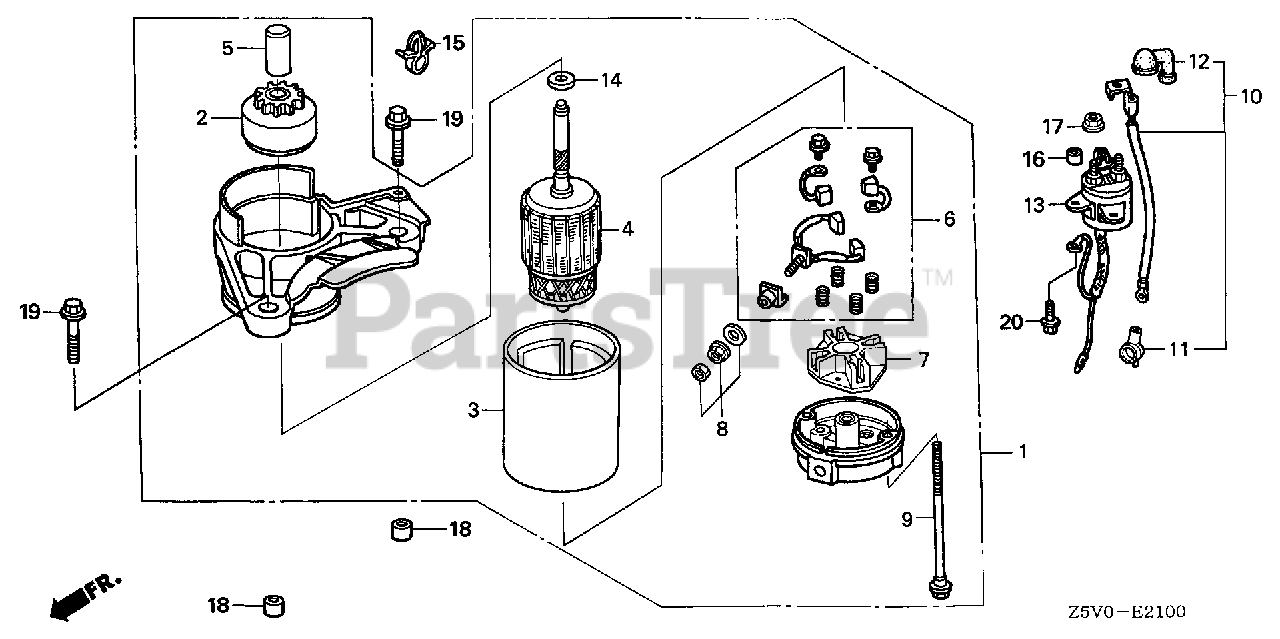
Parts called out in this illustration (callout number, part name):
1	STARTER MOTOR ASSY.
2	DRIVE ASSY.
5	STOPPER SET, PINION
6	BRUSH SET
7	HOLDER, BRUSH
8	NUT SET, TERMINAL
9	BOLT, THROUGH
10	WIRE, MAGNETIC SWITCH
11	COVER, STARTER TERMINAL
12	COVER, MAGNETIC SWITCH TERMINAL
13	SWITCH ASSY., STARTER MAGNETIC
14	WASHER, THRUST
16	COLLAR (6.5X11X10)
17	NUT-WASHER (6MM)
18	PIN, DOWEL (10X12)
19	BOLT, FLANGE (8X35)
20	BOLT, FLANGE (6X25)
